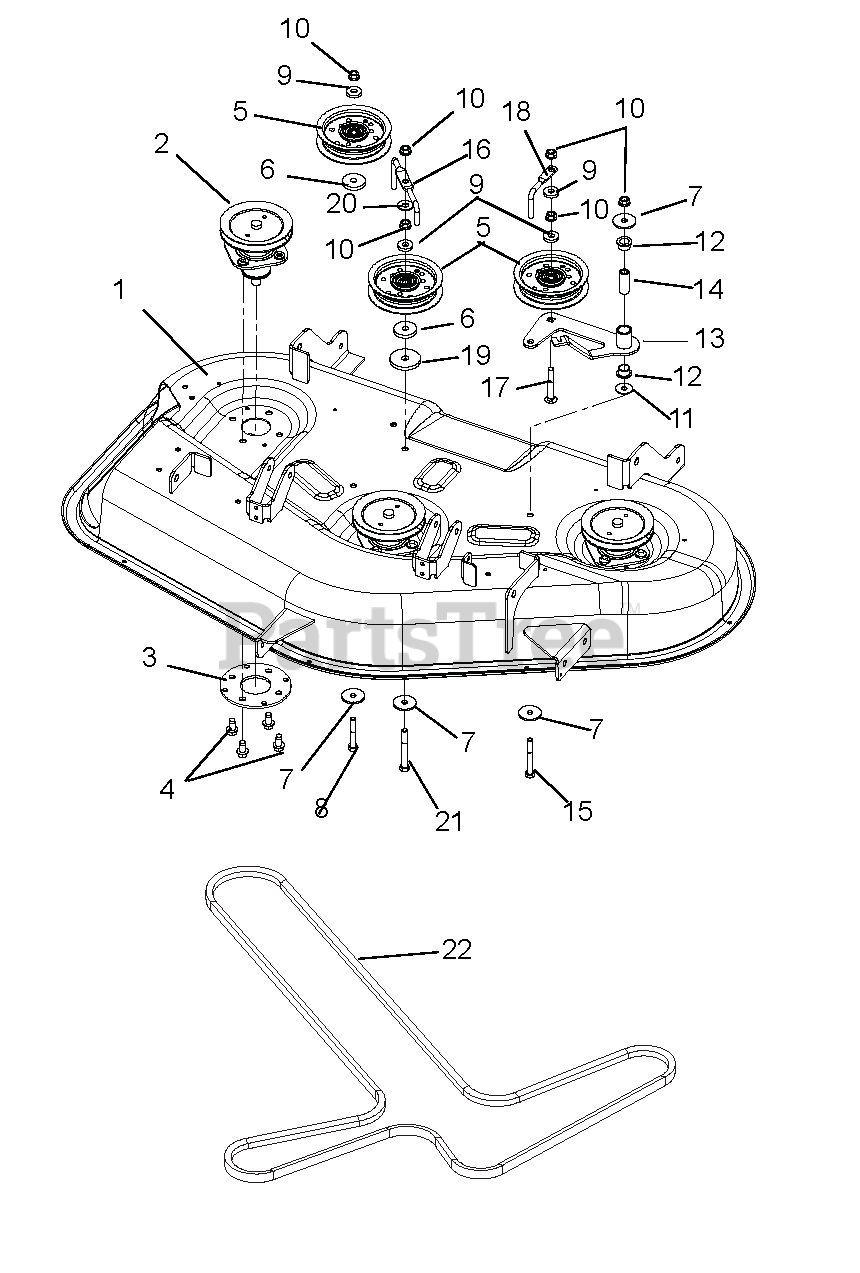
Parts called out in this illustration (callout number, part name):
1	WMT, 42" ZOOM DECK - CE
2	KIT, DECK SPINDLE ASM (42)
3	PLATE-REINF, SPINDLE
4	@SCR-TAP .38-16X.75 HWH TR YWZ
5	ASM, IDLER 4"
6	WSHR,FLT STL.406X1.50X.245YWZC
7	WSHR-FL-STL .380X1.50X.125YWZC
8	@BLT-HEX .38-16X2.25 GR5 YWZC
9	WSHR-FL-STL .406X1.00X.188 YWZ
10	@NUT-LK-TOP-FLG .38-16 YWZC
11	WSHR-FL-STL .375X1.125X.065YWZ
12	BSHG-FLG, .625X.750X.500X1.00
13	WMT, IDLER ARM
14	SPACER, .375IDX.625ODX1.66 PM
15	@BLT-HEX .38-16X2.75 GR5 YWZC
16	WIREFORM, BELT FINGER
17	@BLT-RDHDSQNK .38-16X2.50 G5YZ
18	WIREFORM, BELT FINGER
19	WSHR-FL-STL .469X2.00X.25 YWZC
20	@WSHR-FL-STL.438X1.00X.083 YWZ
21	@BLT-HEX .38-16X3.00 GR5 YWZC
22	V-BELT, 4L-WRAPPED
